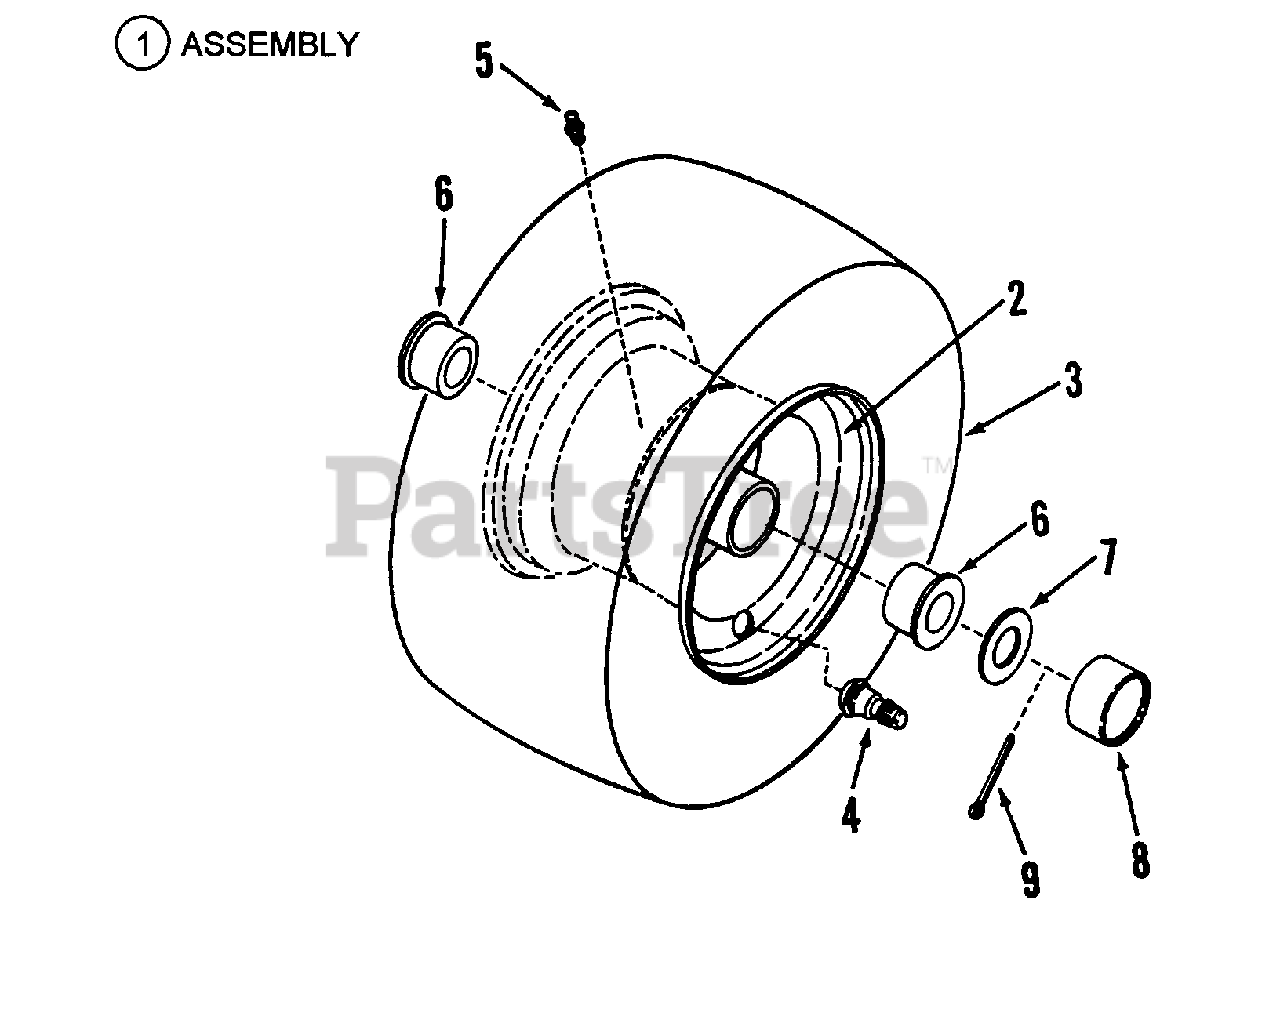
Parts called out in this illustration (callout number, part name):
1	ASSEMBLY, Front Tire & Rim
2	RIM, LT16 Front Wheel
3	TIRE, 15 x 6.00 x 6
4	VALVE, Air
5	FITTING, Lube 1/4-28 Tapered Thread
6	BEARING, Wheel
7	WASHER, 49/64 x 1-1/2" Flat
8	COVER, Dust
9	PIN, 5/32 X 1" Cotter
